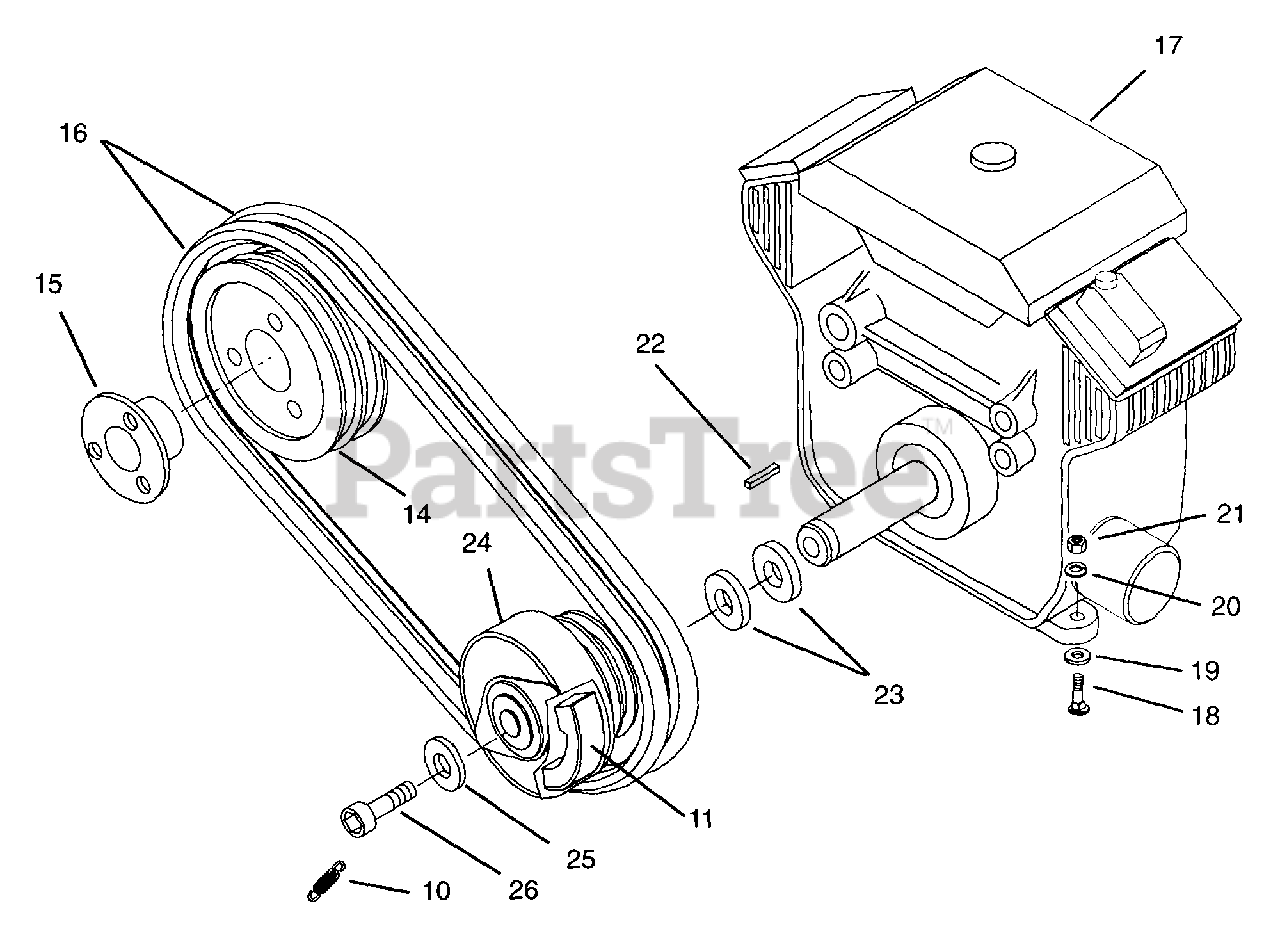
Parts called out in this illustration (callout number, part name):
10	Spring-Clutch
11	Shoe-Clutch
15	Bushing SK x 1.50
16	V-Belt-Set of 2
17	25 H.P. Kohler Command PS-68548
18	Bolt-Round Head-Square Neck .38-16 x 2.00
19	Washer-Flat Steel .438 x 1.0 x .083
20	Washer-Lock .38 x .094
21	Nut-Hex .38-16-Grade 2
22	Key-Square .25 x .25 x 2.50
23	Shim
24	Clutch-1.25 Bore
25	Washer 25 H.P.
26	Screw-Socket Head .43-20 x 1.50
